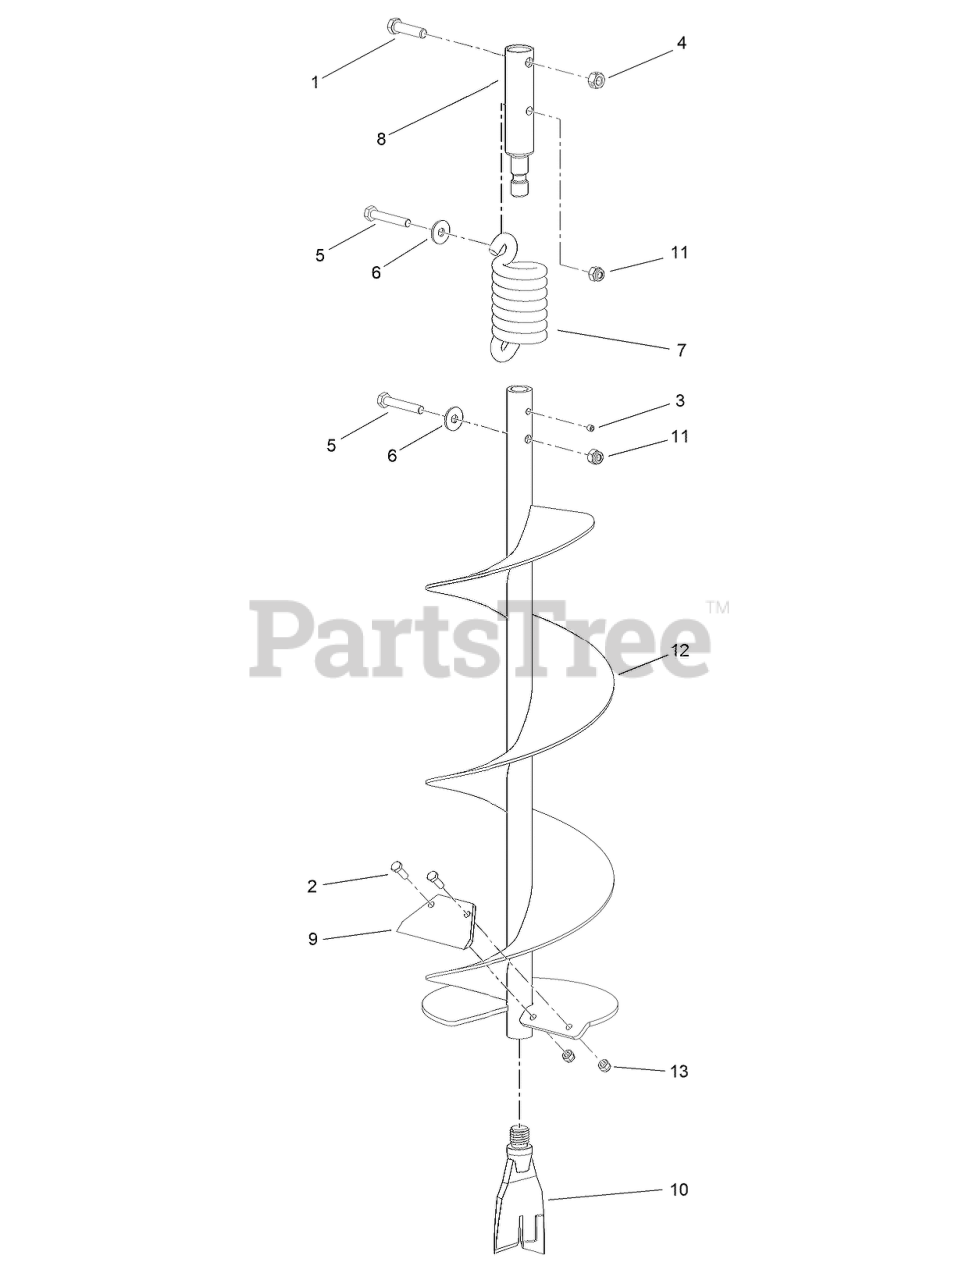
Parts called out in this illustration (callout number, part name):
1	SCREW-HHCS
2	SCREW-HHCS
3	SCREW-SCPC
4	NUT-HEX
5	SCREW-HHCS
6	WASHER-FLAT
7	SPRING-SHOCK
8	TOP-SHOCK
10	FISHTAIL POINT
11	NUT-HEX
12	AUGER-8 INCH
13	NUT-HEX
